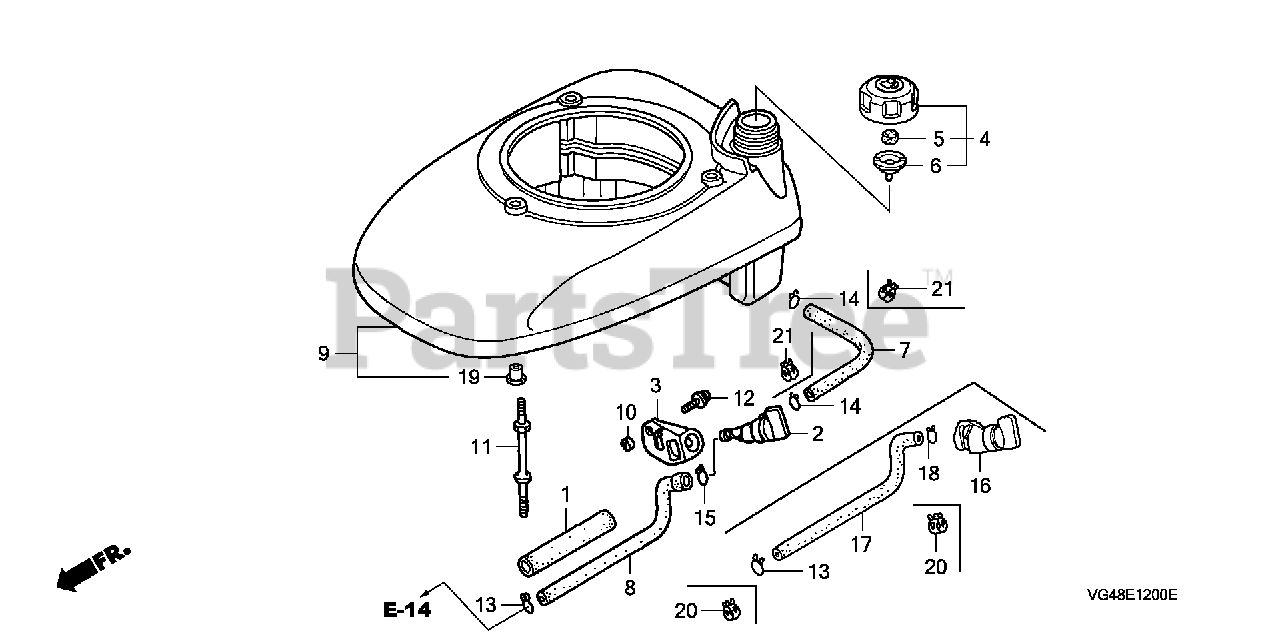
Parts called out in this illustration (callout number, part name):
1	RUBBER, SUPPORTER (107MM)
2	PETCOCK ASSY.
3	BRACKET, PETCOCK
4	CAP ASSY., FUEL TANK
5	SPONGE, FUEL CAP BREATHER
6	GASKET, FUEL CAP
7	TUBE, FUEL TANK
7	TUBE, FUEL (5.3X150) (FKM)
7	BULK HOSE, FUEL (5.5X3000) (5.3X150)
8	TUBE, FUEL
9	COVER, FAN *R280* (POWER RED)
10	COLLAR, FR. TURN SIGNAL
11	BOLT, STUD (H=42.5MM)
12	SCREW-WASHER (5X10)
13	CLIP, TUBE (B8)
14	CLIP, TUBE (B10)
15	CLIP, TUBE (C9)
16	PETCOCK ASSY.
17	TUBE, FUEL
17	TUBE, FUEL (FKM)
18	CLIP, TUBE (B8)
19	COLLAR, FAN COVER
20	CLAMP, TUBE (D8)
21	CLAMP, TUBE (D10)
